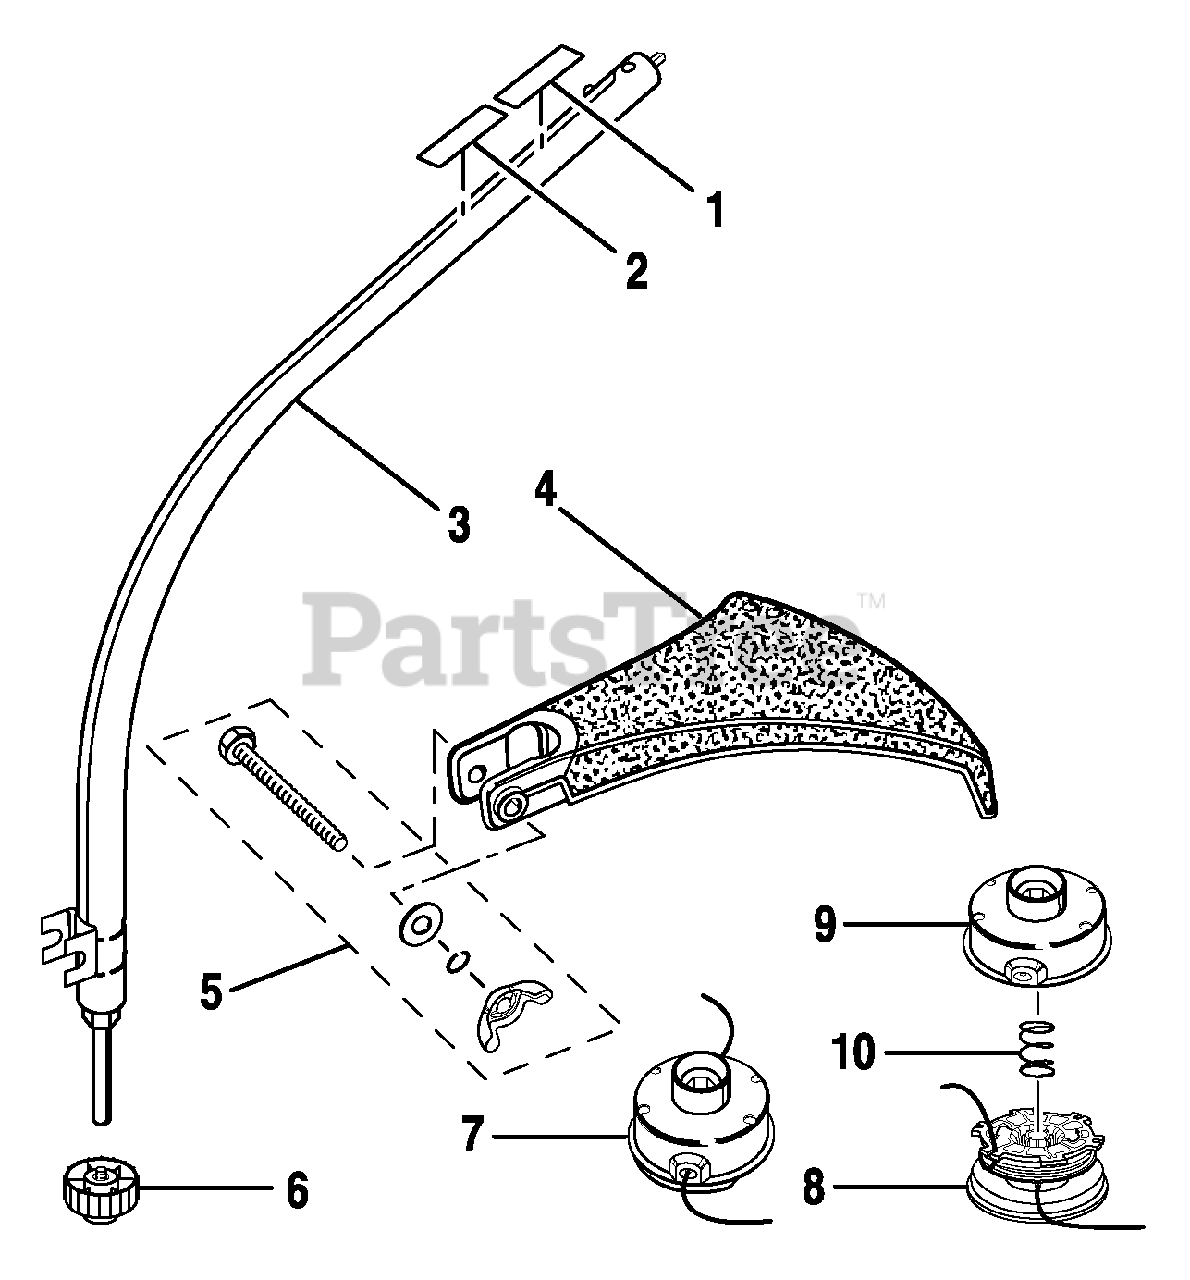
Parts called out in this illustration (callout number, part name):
1	Expand-it Label
2	Warning Decal
3	Curved Shaft Assembly
4	Grass Deflector
5	Fastener Kit
6	Spool Retainer (Black)
7	Complete String Head (.080 in.)
8	Spool and String (.080 in.) w/Spring
9	Housing and Eyelet
10	Compression Spring
